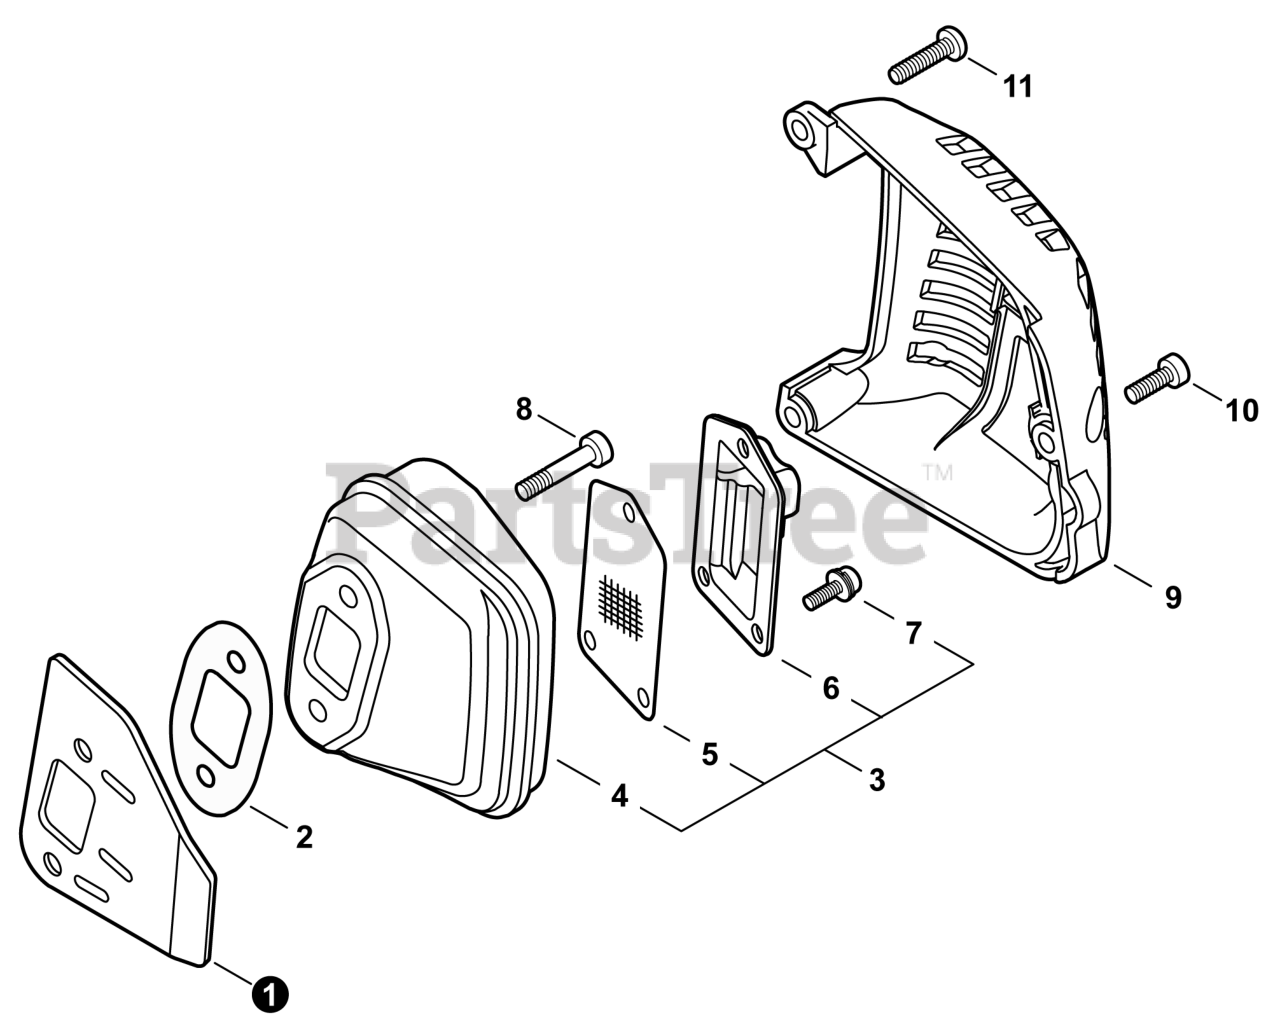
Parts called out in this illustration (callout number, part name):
1	HEAT SHIELD, EXHAUST
2	GASKET, EXHAUST
3	MUFFLER ASSY
4	MUFFLER
5	SCREEN, SPARK ARRESTER
6	GUIDE, EXHAUST
7	SCREW 4x10
8	BOLT 5x40
9	COVER, MUFFLER
10	BOLT, TORX 5x16
11	BOLT, TORX 5x20
